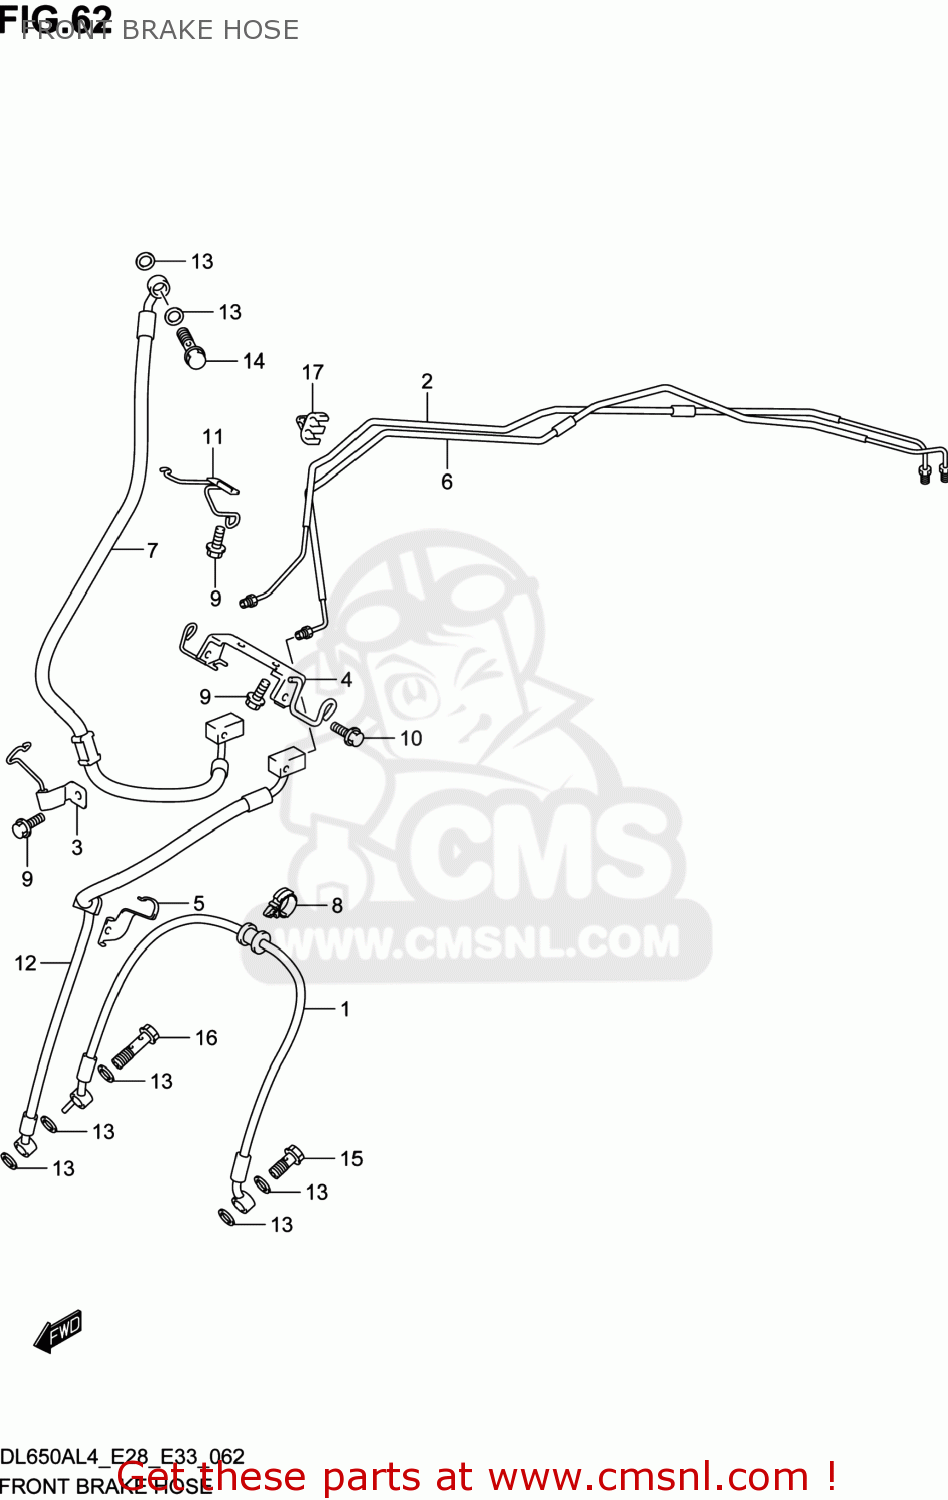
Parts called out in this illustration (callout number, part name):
1	HOSE,FR BRAKE NO.2
2	PIPE,FR BRAKE NO.1
3	CLAMP,FR BRAKE HOSE
4	CLAMP,FR BRAKE HOSE NO.2
5	CLAMP,FR BRAKE HOSE,R
6	PIPE,FR BRAKE NO.2
7	HOSE,FR BRAKE NO.1
8	CLAMP
9	BOLT
10	BOLT
11	GUIDE,FR BRAKE HOSE
12	HOSE,FR BRAKE NO.3
13	WASHER(10X15X1.5)
14	BOLT UNION
15	BOLT UNION
16	BOLT UNION
17	CLAMP
